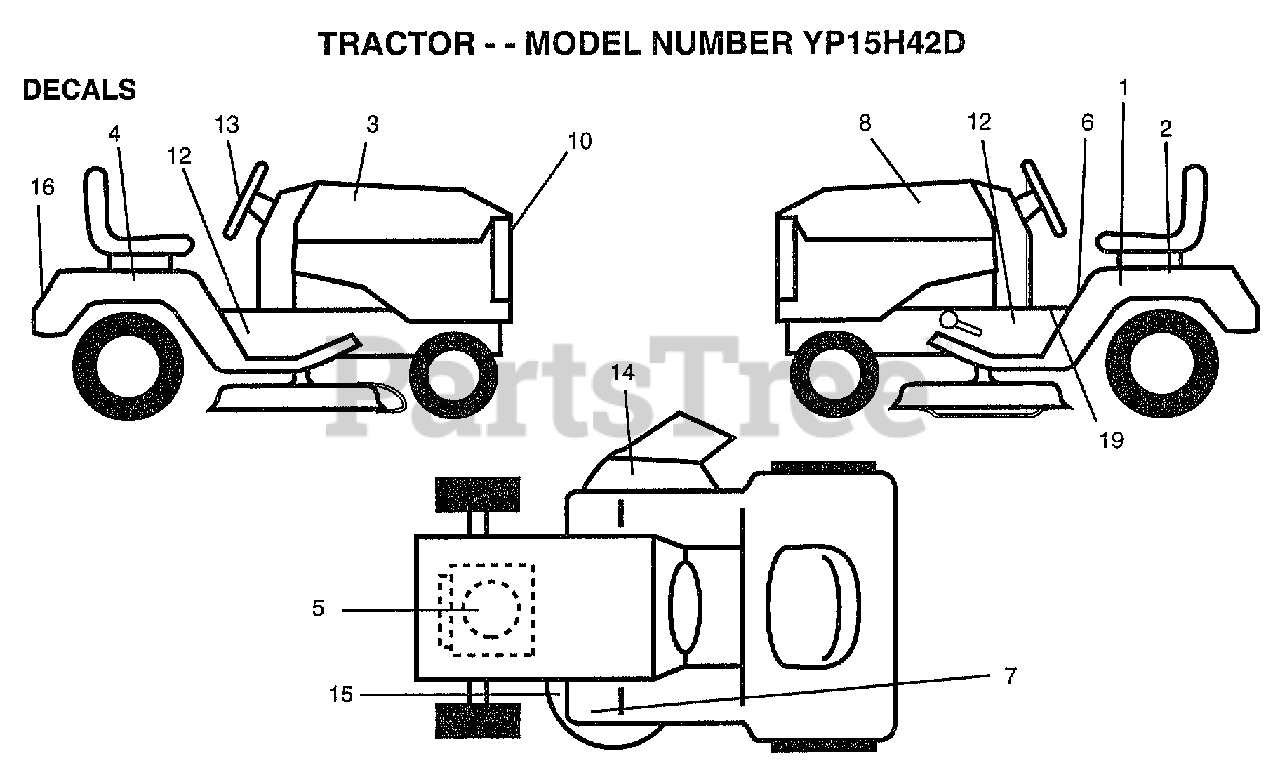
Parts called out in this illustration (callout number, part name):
1	DECAL.BATRY.3-3908
2	DECAL FENDER LH
3	"DECAL HOOD,RH"
4	DECAL FENDER RH
6	DECAL.CAUT.ENG/FR
7	DECAL T
8	"DECAL HOOD,LH"
12	DECAL CHASSIS
13	DECAL INS STRG WH
14	"DECAL, WARNING"
15	"DECAL-SCHEM,BELT"
16	DECAL FENDER
19	DECAL SADDLE OPER
